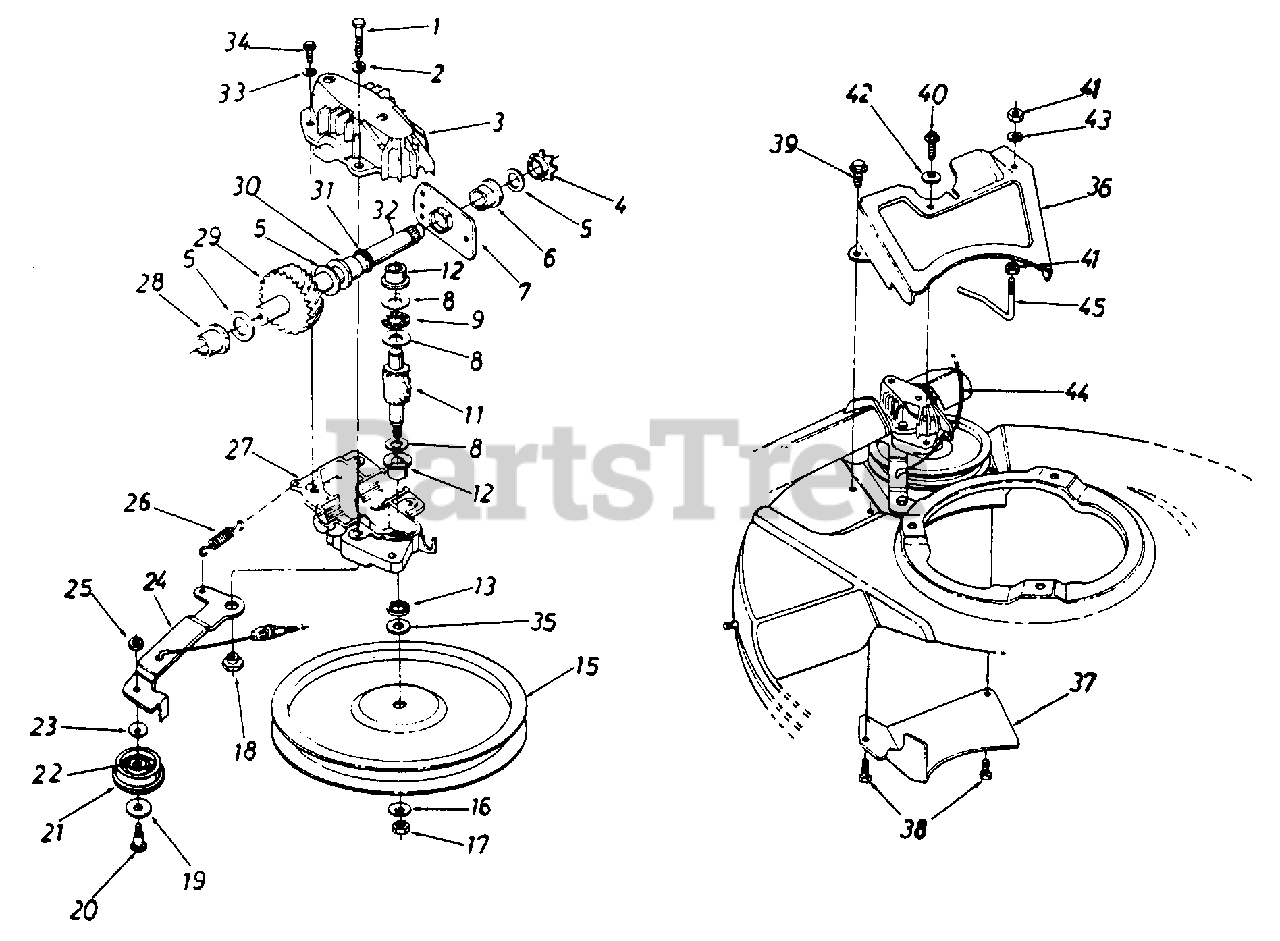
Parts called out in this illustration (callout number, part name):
1	SCREW-HEX
2	L-Wash. 1/4" I.D.
3	HOUSING HALF-UPPER
4	SPROCKET-7T
5	WASHER-FL
6	BEARING-HEX FLANGE
8	WASHER-THRUST.382 X .684
9	BEARING-THRUST
11	SHAFT-PINION 11 T
12	BEARING-FLANGE
13	SEAL-OIL-.375 ID
16	WASHER-SPRING BELL
17	NUT-LH THD-1/4 X 28
18	SPACER-SHLD
19	WASHER-FL .995 X .032
20	SCREW-SHLD
21	PULLEY
22	BEARING-NEEDLE
23	WASHER-SPRING BELL
24	BRACKET ASSY-IDLER
25	NUT-HEX 1/4-28
26	SPRING-EXTENSION
27	HOUSING HALF-LOWER
28	BEARING-FLANGE
29	SHAFT-ASSY W/GEAR
30	BEARING-FLANGE
32	SHAFT-ASSY W/GEAR
33	WASHER-LOCK-#10
34	SCREW-HEX WASH HD TAP
35	WASHER-HEX
39	SCREW-HEX WASH SF TAPP
40	SCREW-HEX B-TAP 1/4-.62
41	NUT-HEX 1/4-20
42	WASHER-SPRING BELL
43	LOCK WASHER 1/4 DIA
44	CABLE-CLUTCH
45	GUARD-BELT
